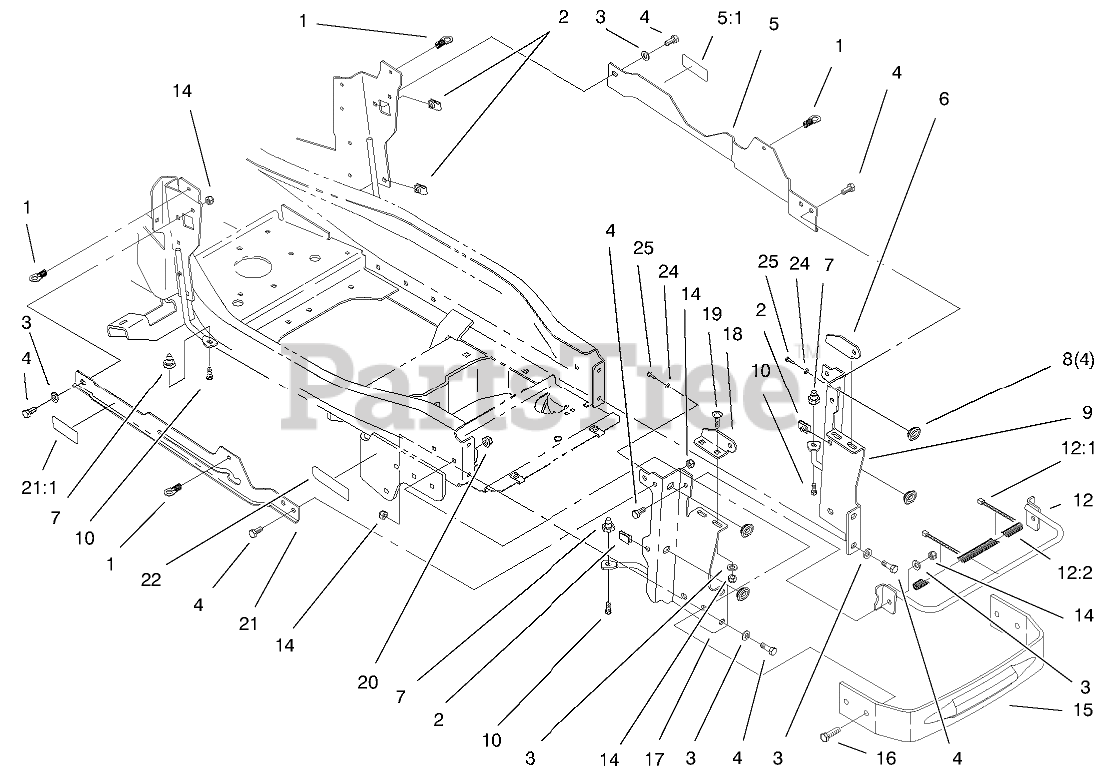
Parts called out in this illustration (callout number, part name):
1	LATCH ASM
3	WASHER-PLAIN
4	SCREW-HH
5	Support ASM (Only On: 73545)
5	Support ASM (Only On: 73546)
5:1	Decal-Warning (Only On: 73545)
5:1	Decal-Warning (Only On: 73546)
6	BRKT-LOWER HINGE LH (BLACK)
7	MOUNT-SIDEPANEL
8	GROMMET
9	SUPPORT-HOOD, LH
10	SCREW-PLASTITE
12	ASSEMBLY - HOOD SUPPORT
12:1	COVER-BRACE
12:2	TIE-CABLE
14	NUT-LOCK, NI
15	BUMPER-FRAME
16	SCREW-HH
17	SUPPORT-HOOD, RH
18	BRKT-LOWER HINGE RH
19	SCREW-CARR
20	NUT-LOCK, NI
21	Support ASM (Only On: 73545)
21	Support ASM (Only On: 73546)
21:1	Decal-Warning (Only On: 73545)
21:1	Decal-Warning (Only On: 73546)
22	DECAL-ATTACH A-MATIC
24	Washer-Flat (Only On: 73546)
25	Screw-HH TAP (Only On: 73546)
